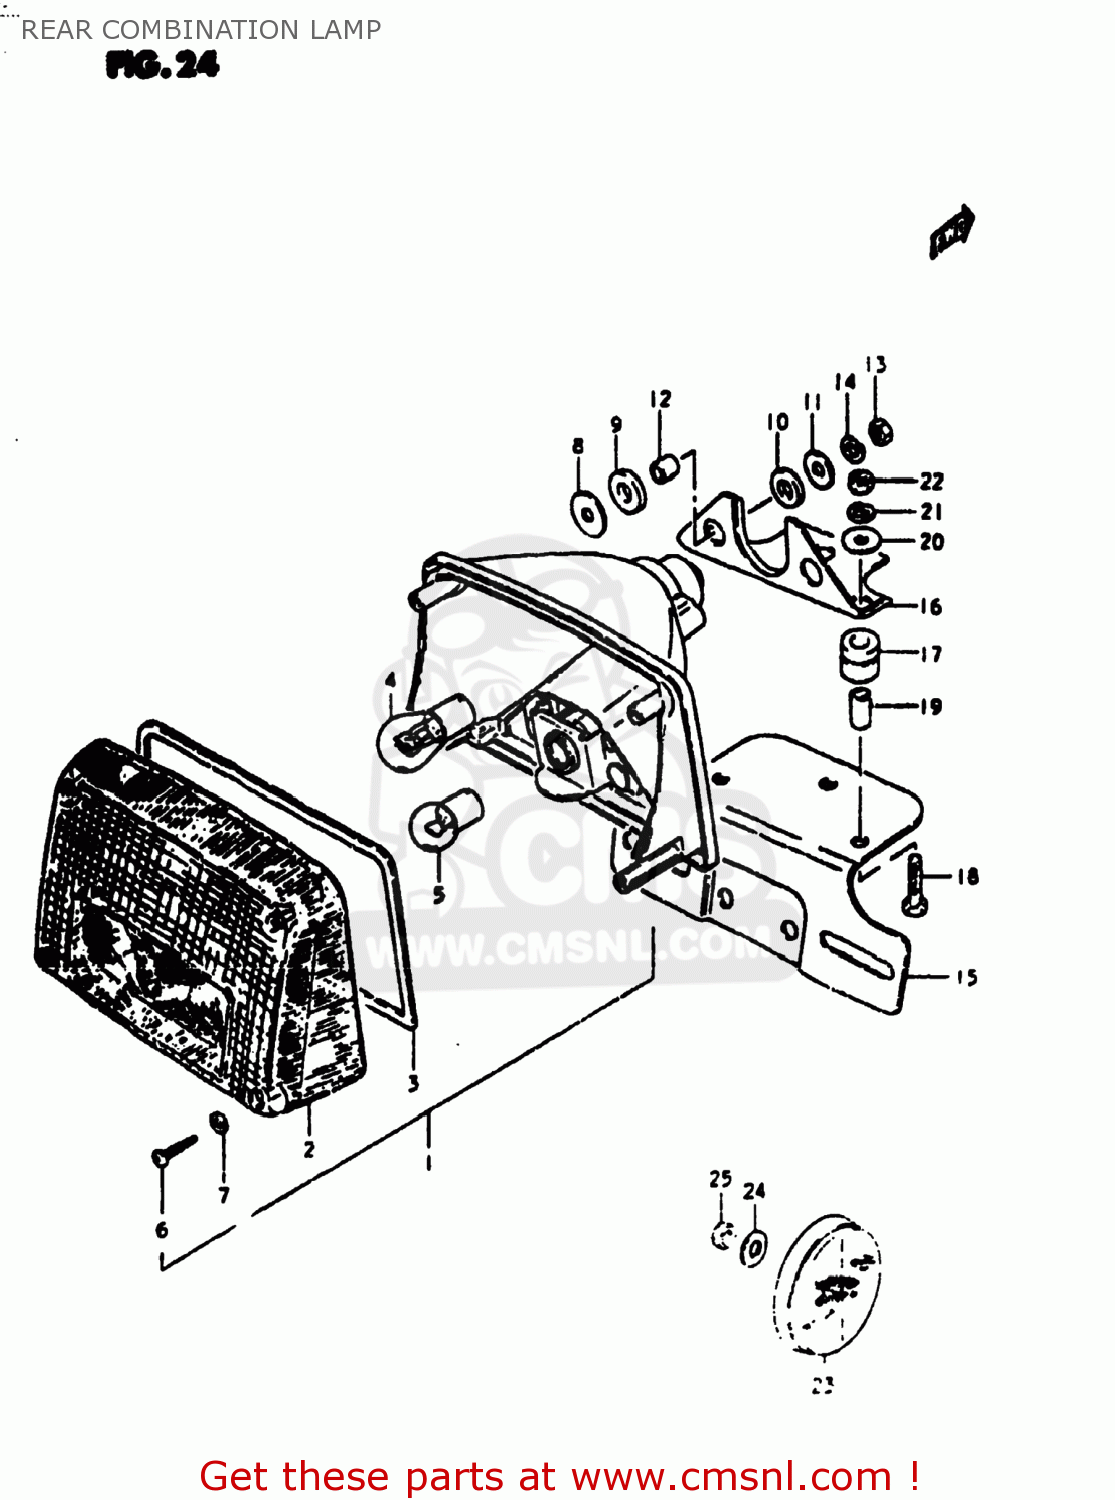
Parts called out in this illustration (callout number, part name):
1	LAMP ASSEMBLY,REAR COMBINATION
2	LENS
3	GASKET (NAS)
4	BULB(12V23W)
5	BULB
6	BOLT
7	GASKET (NAS)
8	WASHER
9	CUSHION
10	CUSHION
11	WASHER(6,5X22X1.6)
12	SPACER(6.1X9X7.5)
13	NUT
14	LOCK WASHER
15	PLATE,REAR LICENSE
16	BRACKET,LICENSE PLATE
17	CUSHION, BRACKET
18	BOLT
19	SPACER (6.1X8X15.5)
20	WASHER
21	LOCK WASHER
22	NUT
23	REFLEX REFLECTOR,RR
24	WASHER
25	NUT
